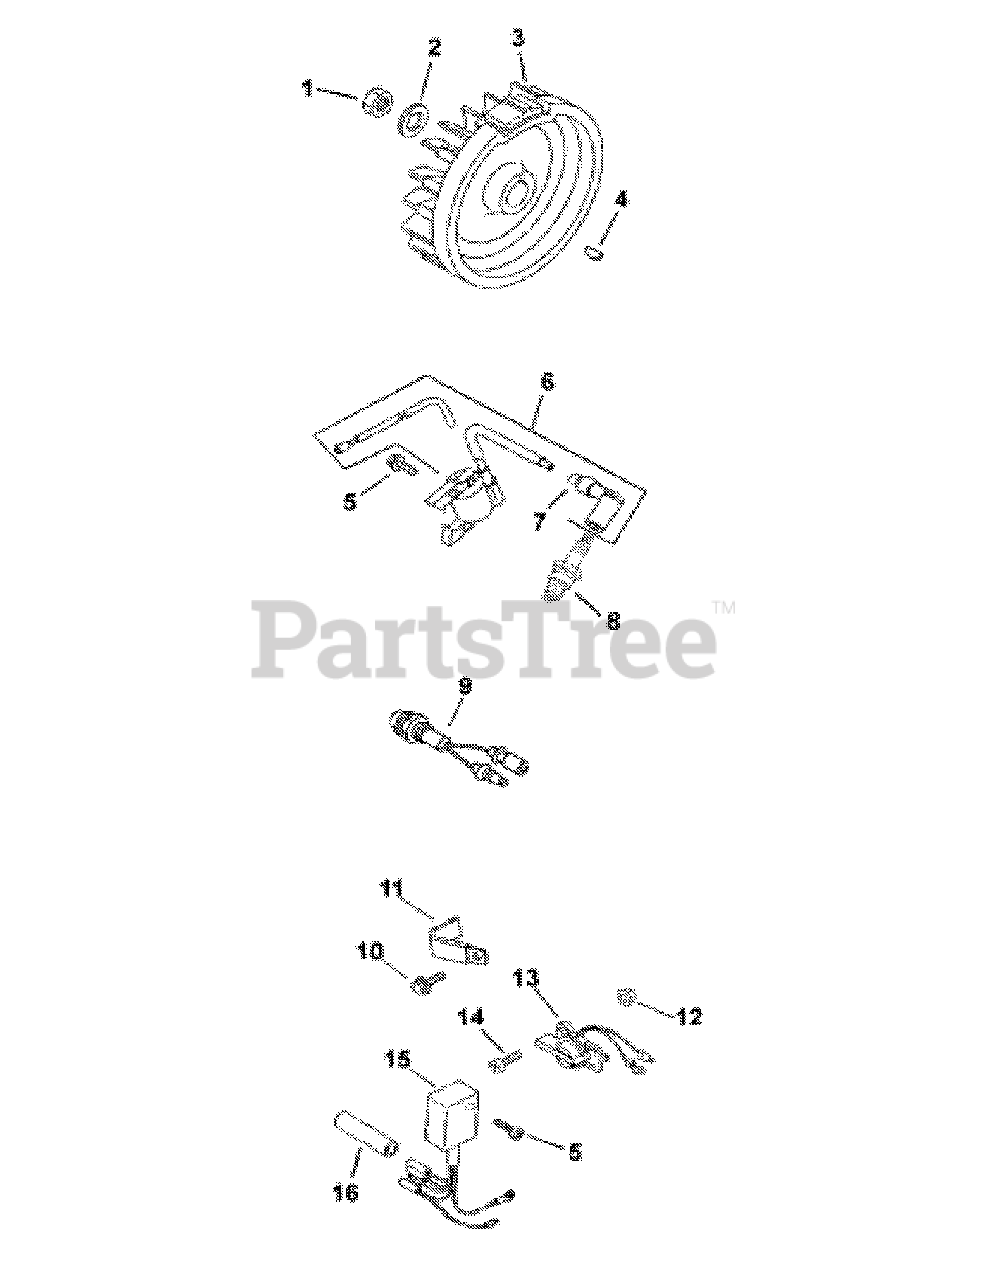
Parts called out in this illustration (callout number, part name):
2	Flywheel washer
6	Ignition Module
7	Spark Plug Cap
8	Spark Plug
12	Stop Switch Nut
14	Stop Switch Screw
15	Oil Warning Unit
